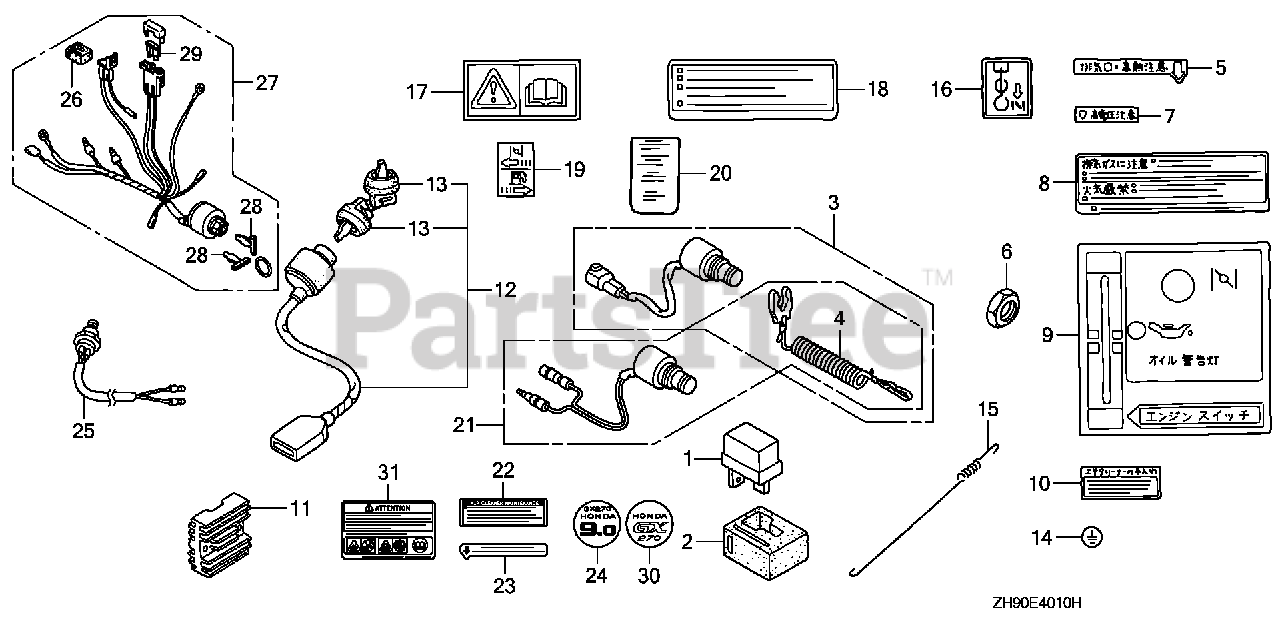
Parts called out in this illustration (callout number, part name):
17	MARK, CAUTION (PICTOGRAPH)
18	LABEL, CAUTION (ENGLISH, ETC.)
19	MARK, CHOKE (EXTERNAL)
20	LABEL, AIR CLEANER CAUTION
